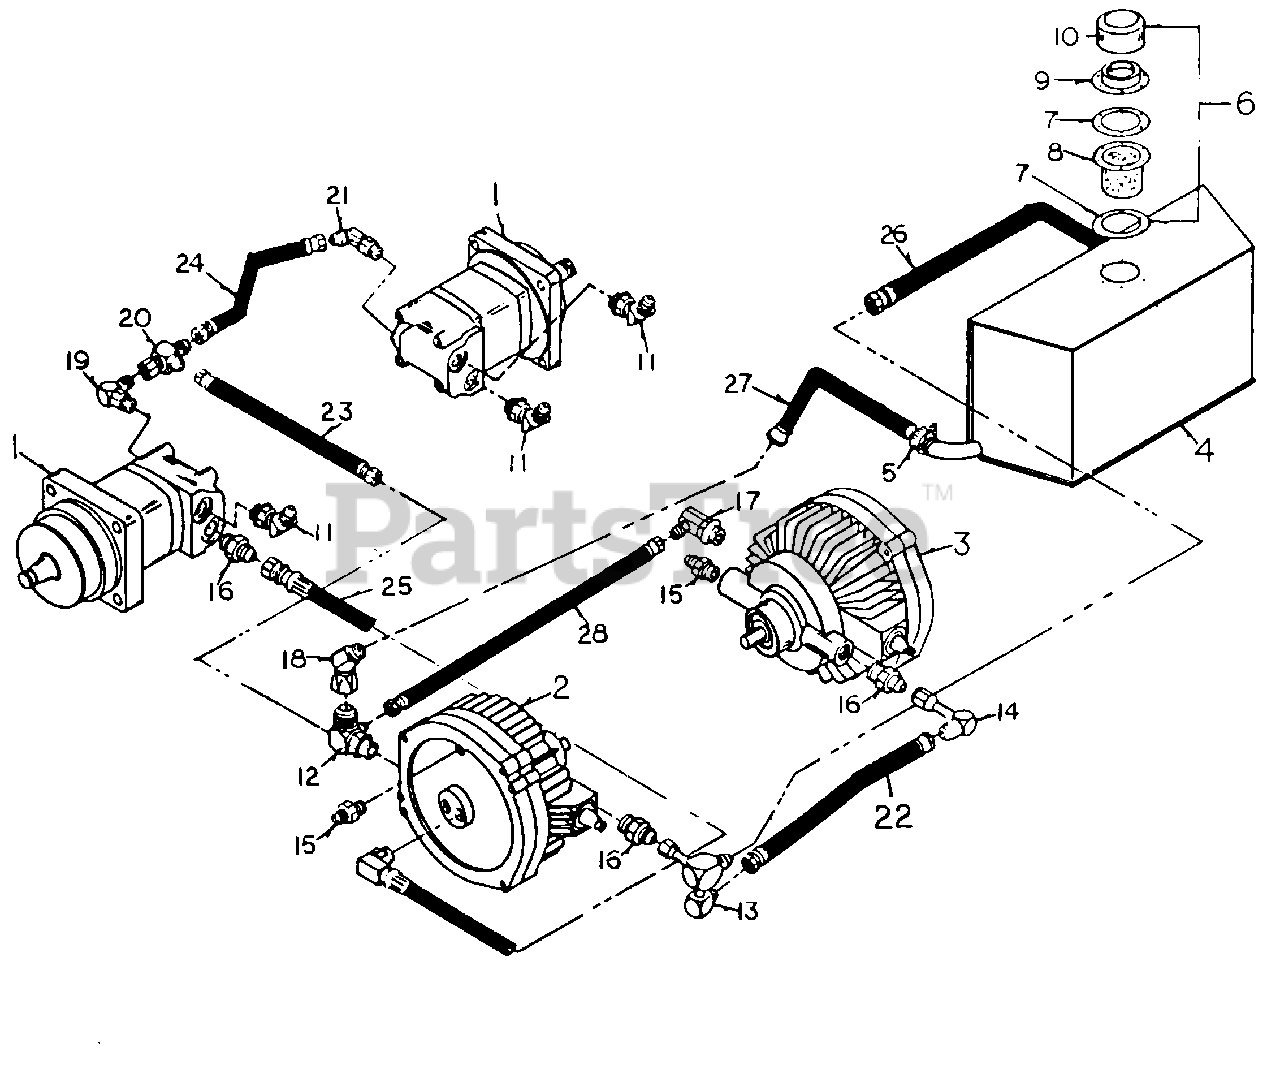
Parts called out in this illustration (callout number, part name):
3	Pump, RH
4	Hydraulic Oil Tank
5	Hose Clamp
6	Hydraulic Fill Cap Assembly 1
8	Strainer
9	Fill Neck
11	Male Tube, 45ø Male O-ring Adapter
13	Special Adapter
14	Male Tube, 90ø Female Swivel Adapter
15	Male Tube, Male O-ring Adapter
16	Male Tube, Male O-ring Adapter
17	Male Tube, 90ø Male O-ring Adapter
18	Male Tube, 45ø Female Swivel Adapter
19	Male Tube, 90ø Male O-ring Adapter
20	Male Tube, Female Swivel Tee
21	Male Tube, 45ø Female Swivel Adapter
22	Hose, 1/2" ID x 18" Long, Easy Couple
23	Hose, 1/4" ID x 14" Long, Easy Couple
24	Hose, 1/4" ID x 20" Long, Easy Couple
25	Hose, 1/2" ID x 36 1/2" Long
26	Hose, 3/4" ID x 22" Long, Easy Couple
27	Hose, 3/4" ID x 18" Long, Easy Couple
28	Hose, 1/2" ID x 20" Long, Easy Couple
